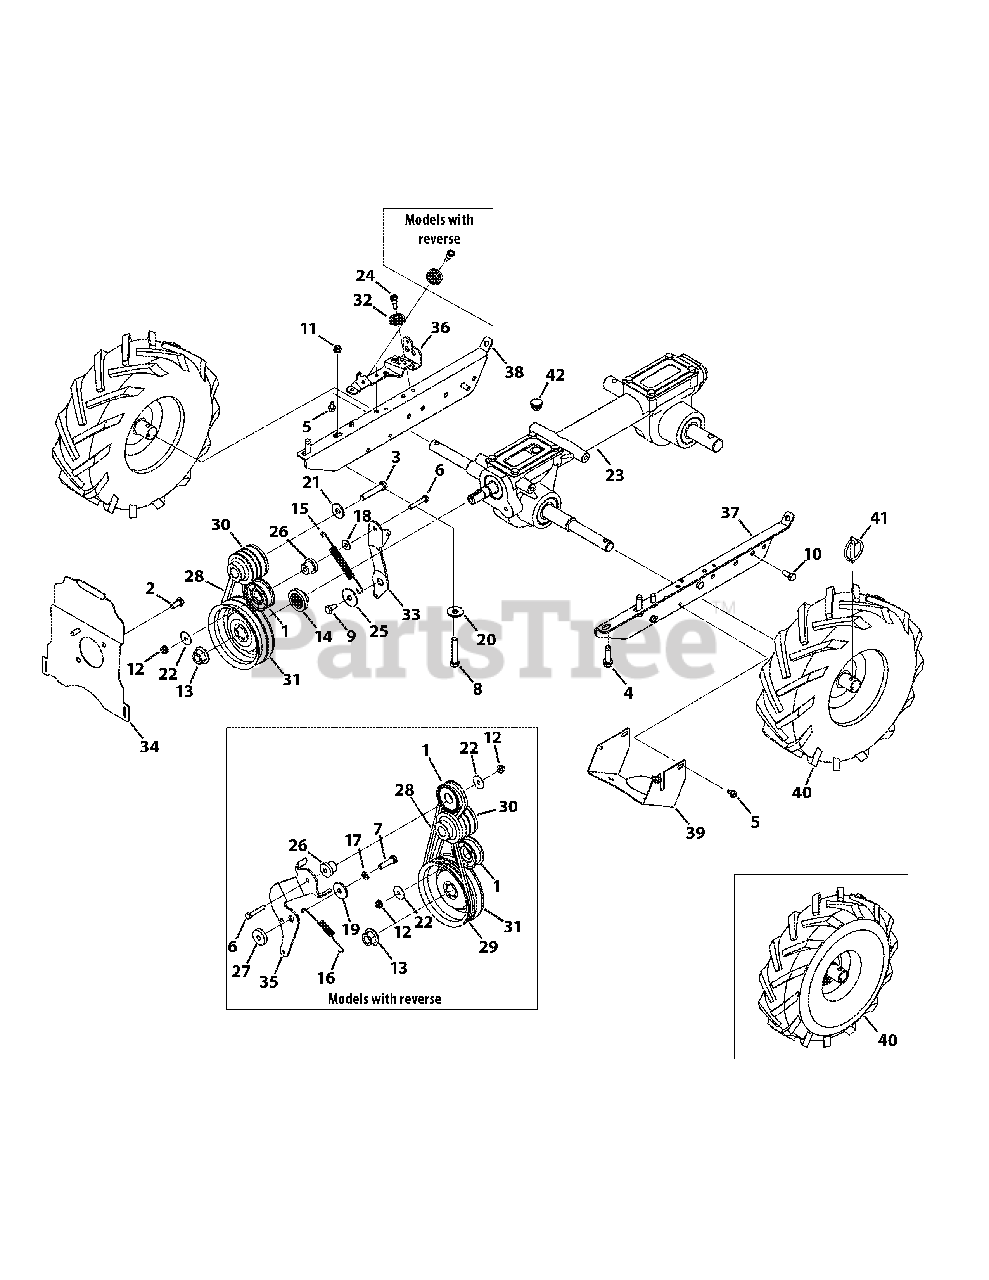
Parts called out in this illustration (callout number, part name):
1	Idler Pulley Assembly, 1.917 OD
2	Hex Head Screw, 5/16-24 x .625
3	Hex Head Screw, 3/8-24 x 2.25
3	Hex Head Screw, 3/8-24 x 2.00
4	Screw, 3/8-16 x 1.250
5	Screw, 1/4-20 x 0.500
6	Hex Head Screw, 1/4-20 x 1.50
7	Hex Head Screw, 5/16-24 x 1.25
8	Hex Head Screw, 5/16-18 x 1.50
9	Hex Head Screw, 5/16-18 x .75, Patch
10	Hex Head Screw, 5/16-18 x .75, Std.
11	Flangelock Nut, 5/16-18
12	Flangelock Nut, 1/4-20
13	Flange Nut, 9/16-18
14	Pulley Hub, 5/8 SPLINE
15	Extension Spring, .480 OD x 5.00 LG
16	Extension Spring, LT5 PTO
17	Washer, Lock, 5/16
18	Washer, Flat, .28 x .74 x .063
19	Washer, Flat, .330 x 1.25 x .120
20	Washer, Belleville, .396 x 1.140 x .095
21	Washer, Bell, .396 x 1.140 x .095
22	Washer, Flat, .265 x 1.0 x .030
23	Transmission Assembly
24	Screw, Shoulder, 1/4-28 x .340 x .335
25	Forward Idler Pivot Spacer
26	Spacer, Shoulder, .260 x .785 x .538
27	Reverse Idler Pivot Spacer
28	V Belt, 4L x 25.375 LG
29	V Belt, 3L x 29.125 LG
30	Engine Pulley, 3L & 4L, B&S
30	Engine Pulley, 3L & 4L Honda
31	Transmission Pulley
32	Cable Roller
33	Forward Idler Bracket
34	Cover Mounting Plate
35	Reverse Idler Bracket
36	Pulley Mounting Bracket
37	LH Mount Frame
38	RH Mount Frame
39	Pulley Shield
40	Wheel, 13 x 5 x 6
40	Wheel Assembly, 11 x 4-4
41	Klik Pin, .25 DIA x 1.56
